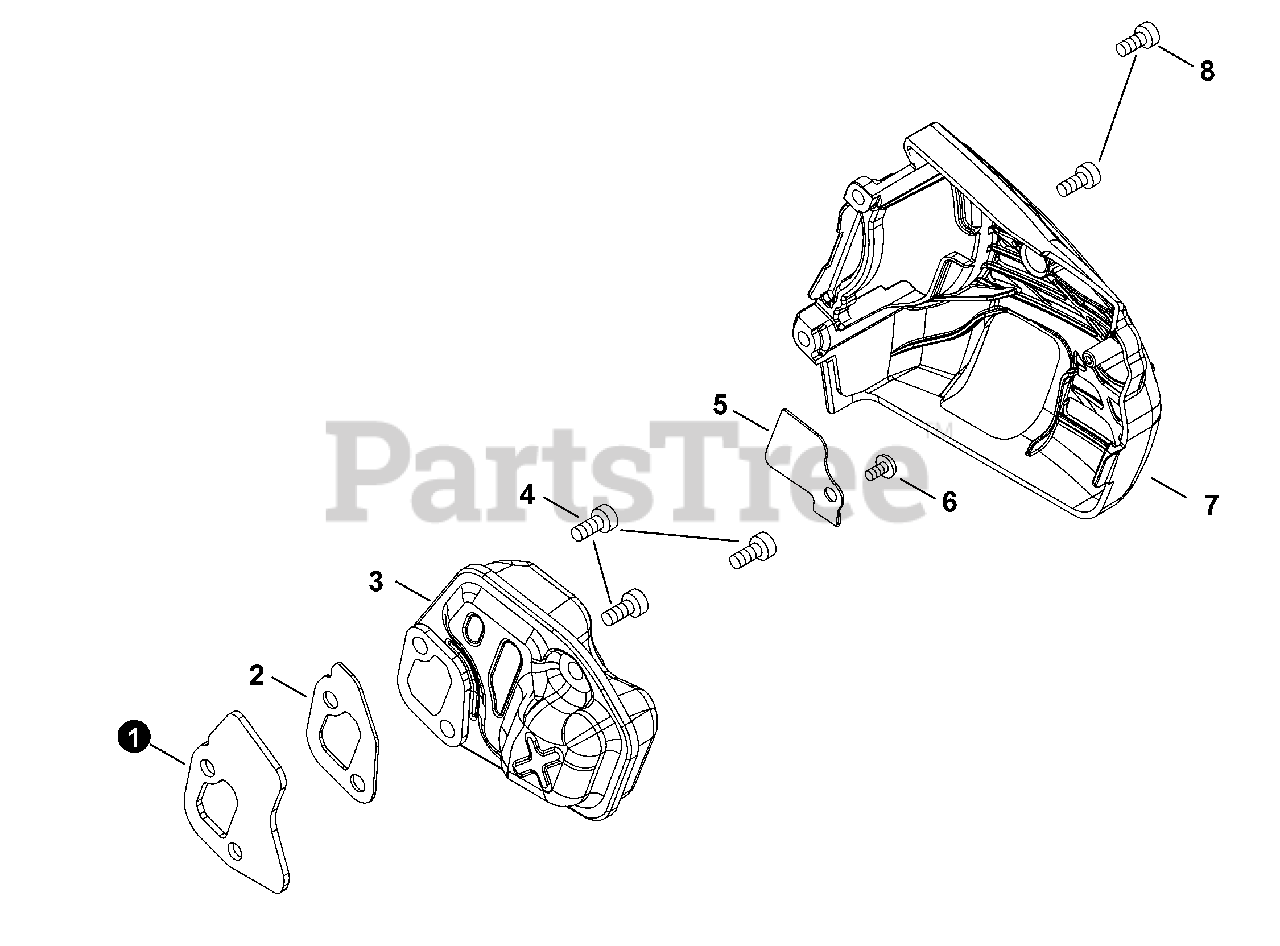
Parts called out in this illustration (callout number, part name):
1	HEAT SHIELD, EXHAUST
2	GASKET, EXHAUST
3	MUFFLER ASSY
4	BOLT, TORX 5×16
5	SCREEN, SPARK ARRESTER
6	SCREW 4×6
7	COVER, MUFFLER
8	BOLT, TORX 4×16
